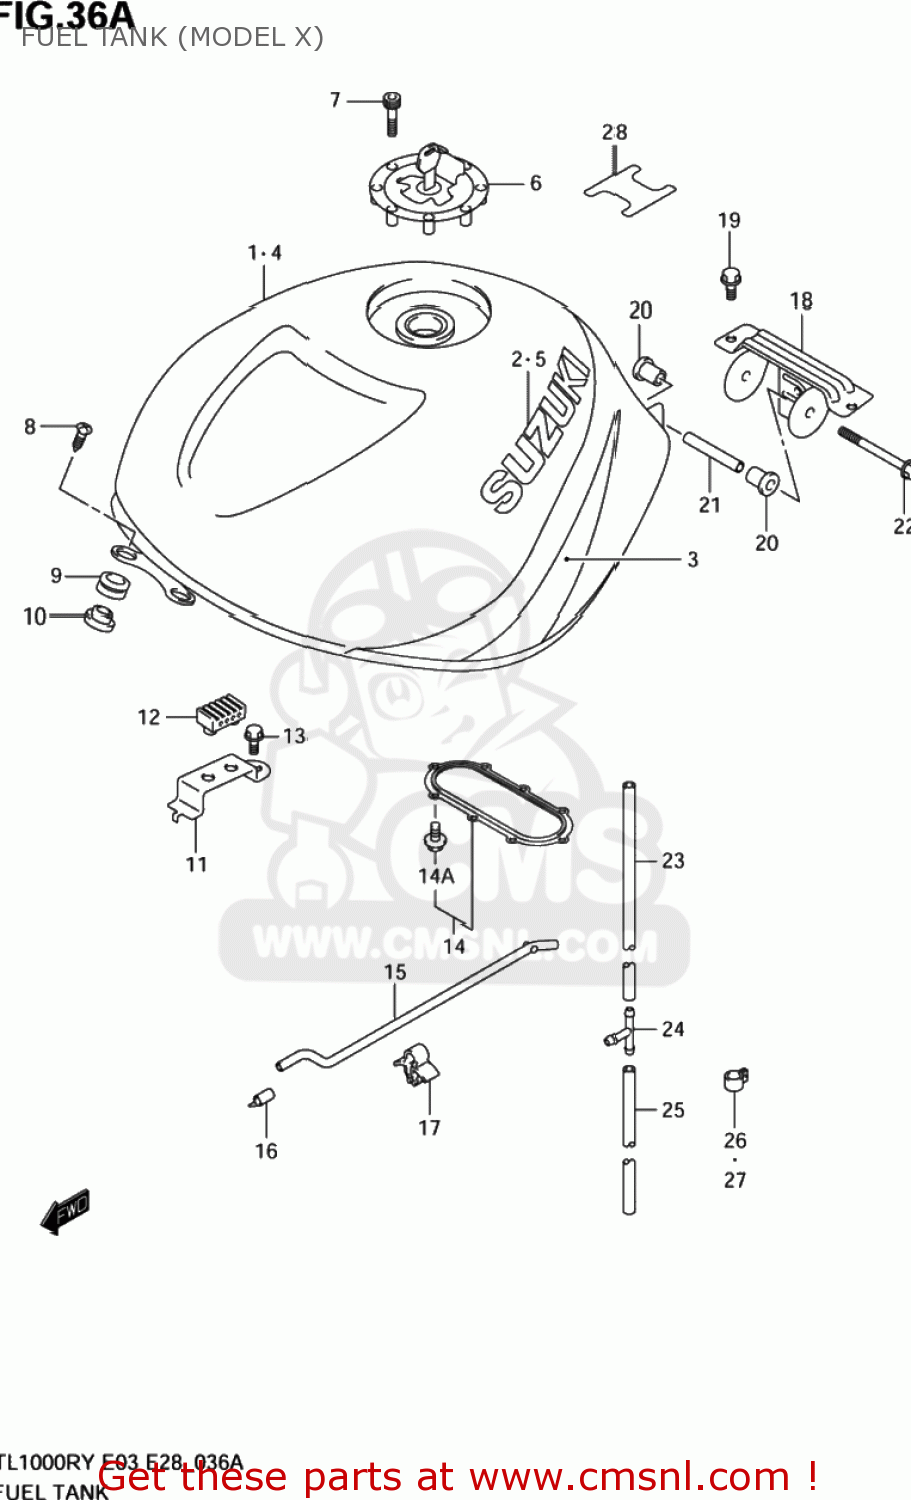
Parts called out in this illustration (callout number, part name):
1	TANK ASSY,FUEL
2	EMBLEM,FUEL TANK
3	TAPE SET,FUEL TANK (BLUE)
4	TANK ASSEMBLY,FUEL
5	EMBLEM,FUEL TANK
6	CAP SET,FUEL TANK
7	BOLT(5X20)
8	SCREW(6X25)
9	CUSHION
10	WASHER
11	BRACKET,FUEL TANK SIDE CUSHION
12	CUSHION,SEAT(40X20X15)
13	BOLT
14	PACKING SET,FUEL PUMP (NAS)
14A	BOLT,FUEL PUMP
15	STAY,FUEL TANK
16	CAP,OD:11
17	CLAMP
18	BRACKET,FUEL TANK RR
19	BOLT
20	CUSHION,FUEL TANK RR
21	SPACER,FUEL TANK RR
22	BOLT
23	HOSE,FUEL TANK DRAIN
24	3 WAY
25	HOSE(7X10.2X600)
26	CLAMP
27	CLAMP
28	LABEL,FUEL TANK INNER
